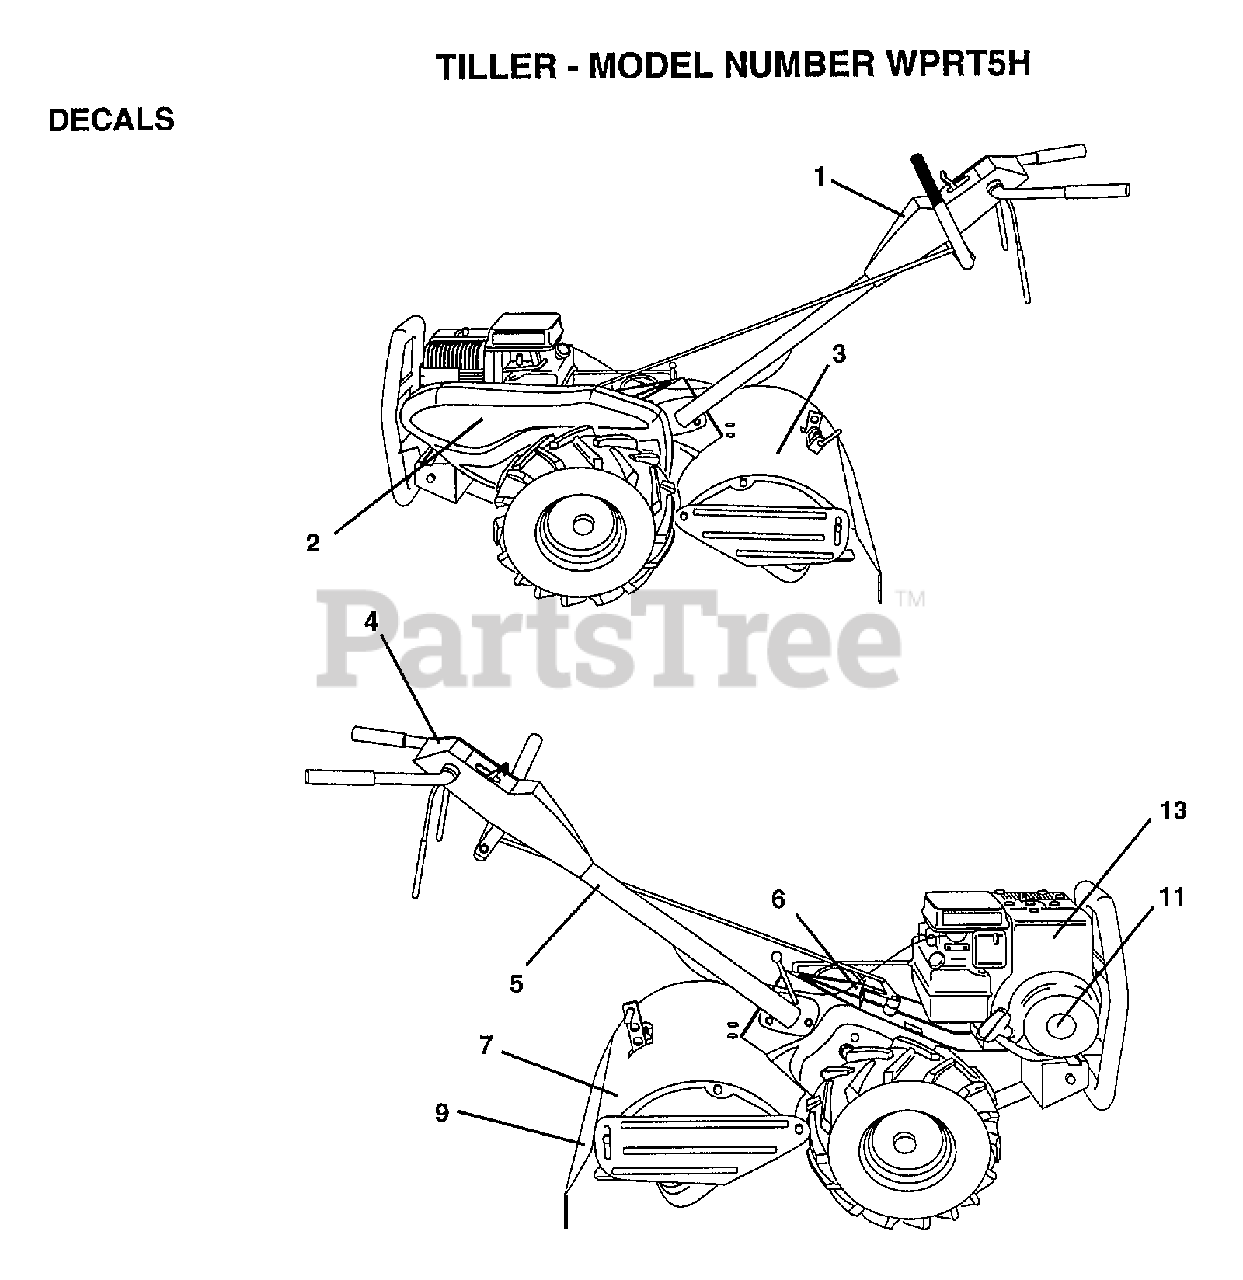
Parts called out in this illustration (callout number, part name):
1	DECAL.PNL.CONTROL
2	DECAL, LOGO
3	DECAL.SHLD.TINE
4	DECAL.INSTRUCTION
5	DECAL TI
6	DECAL CRT
7	DECAL.TINE.SHIELD
9	DECAL TI
